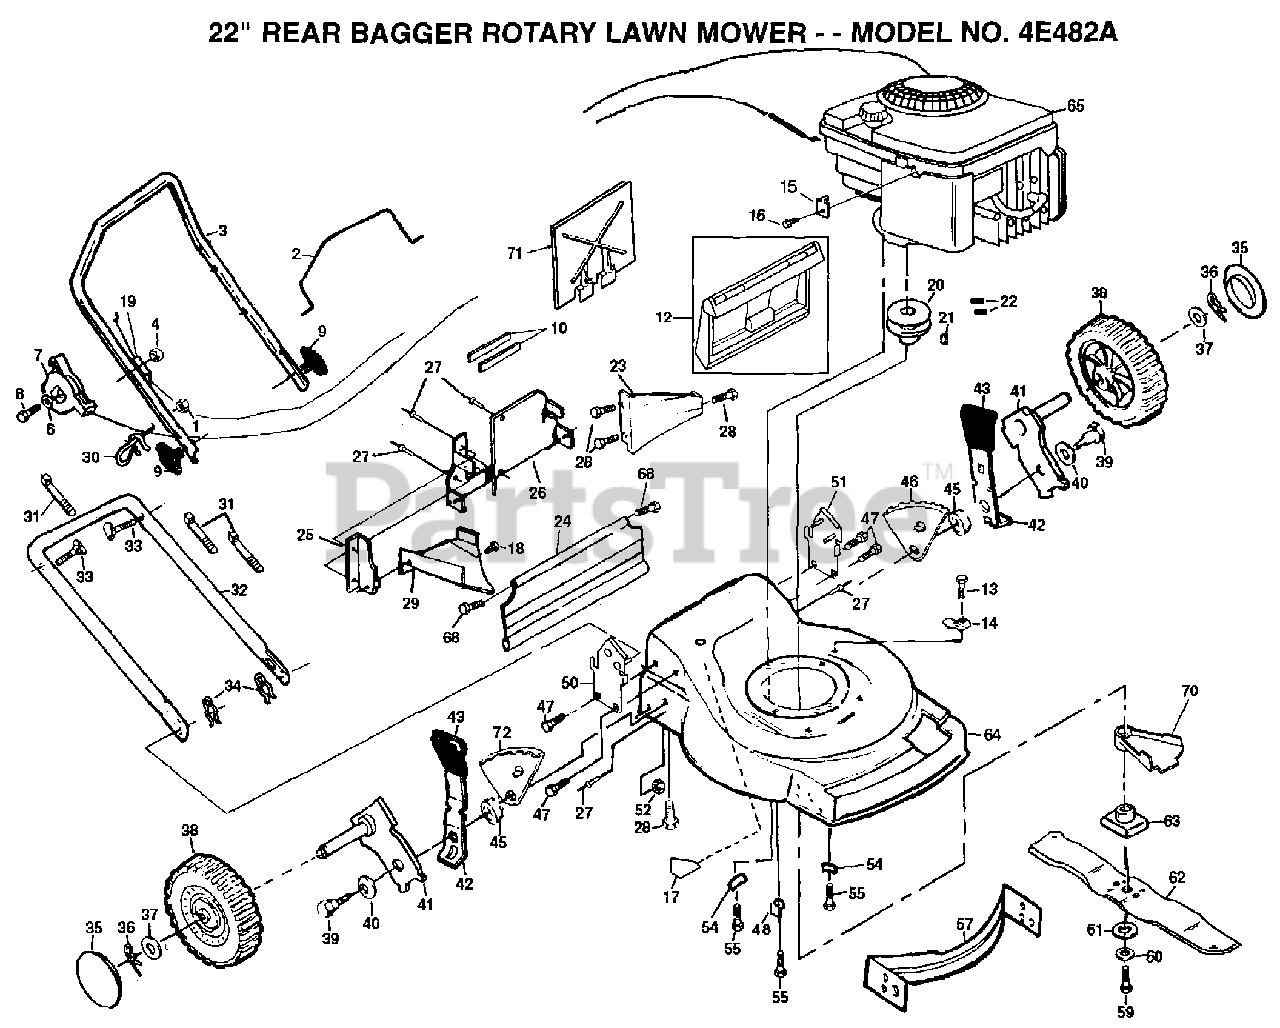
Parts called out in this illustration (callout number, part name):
1	NUT
2	"BAR,CONT"
6	WASHER PM
7	CNTL.THROT.47.5
9	KNOB HANDLE
10	"SEAL,REAR DOOR"
13	TAPPING SCREW
14	GUIDE CLIP PM
15	CABLE CLAMP
17	DECAL HYT
18	SCREW PM
19	"CABLE,ENG ZONE CO"
20	ENGINE.PULLEY.FWG
21	HI PRO KEY PM
22	SCREW
23	REAR BAFFLE
26	PLATE.BACK.22RD
27	BLIND RIVET
28	SCREW
29	DISCHARGE BAFFLE
30	ROPE GUIDE
33	BOLT.HANDLE.LM
34	HAIRPIN COTTER
35	HUB CAP
36	RETAINER CLIP PM
37	WASHER
40	"WASHER, BELLEVIL."
41	AXLE ARM
42	SPRING SELECTOR
43	KNOB PM
47	SCREW
48	DEBRIS SHLD RET
52	LOCKNUT PM
55	SCREW
59	SCREW
60	LOCKWASHER
61	"WASHER,HARDEN"
63	ADAPTOR.BLADE.LM
64	KIT.HSG.22RD.FWGD
68	HINGE SCREW
71	MULCHER PLATE
